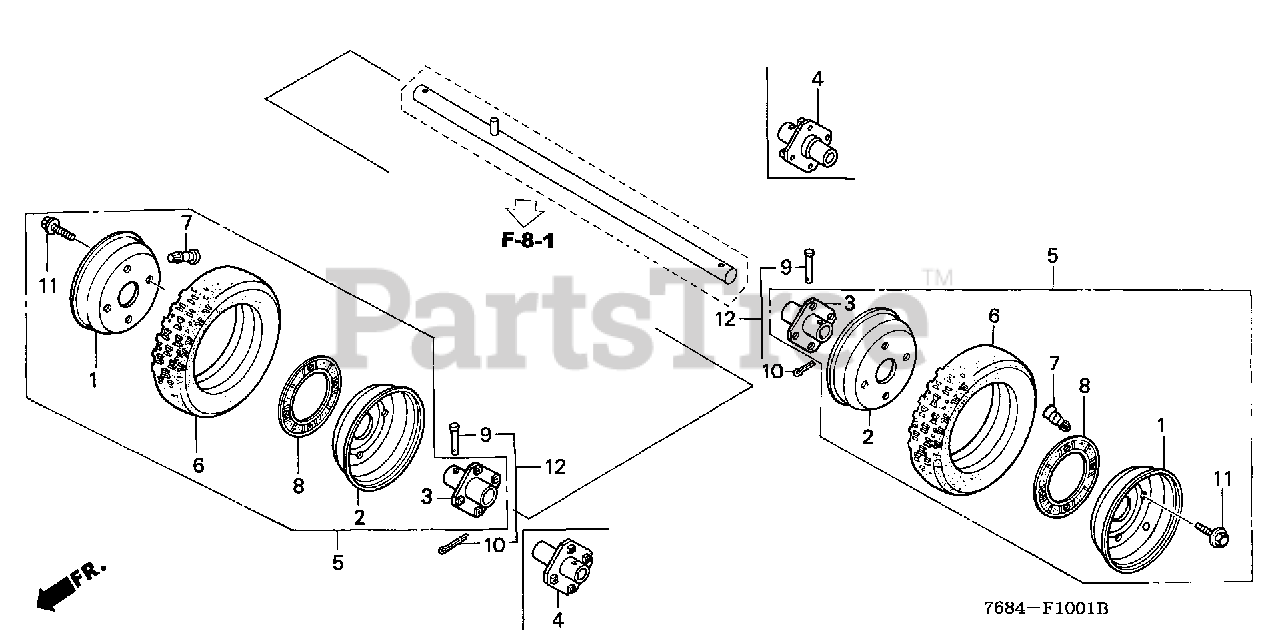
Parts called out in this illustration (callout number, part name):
1	WHEEL A (3SPWX6DCT)
2	WHEEL B (3SPWX6DCT)
4	WHEEL (HUB NOT AVAILABLE: IS PART OF COMPLETE WHEEL 42710-V41-003)
6	TIRE (14X4.00-6)
6	TIRE (14X4.0-6)
7	VALVE, RIM (SCHRADER)
7	VALVE, RIM (TAIHEIYO)
8	GASKET (U-75)
10	PIN, SPLIT (3.0X18)
11	BOLT, FLANGE (8X16)
